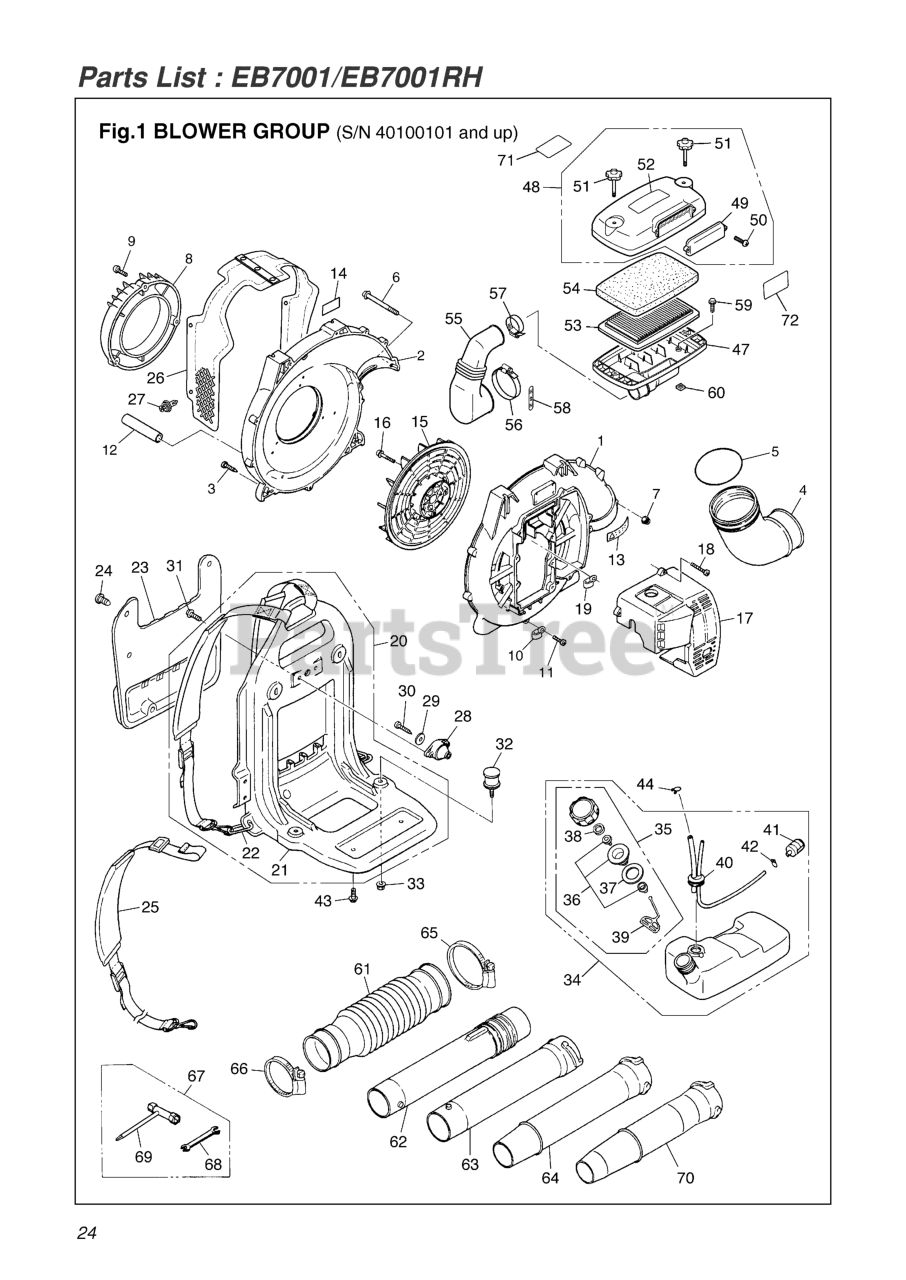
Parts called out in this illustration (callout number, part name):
1	CASE, VOLUTE
2	848-L5C-55B3
3	SCREW, M5 X 25
4	ELBOW
5	O-RING
6	SCREW, M5 X 70
7	NUT (B)
8	COVER, INLET
9	SCREW, M5 X 25
10	CLAMP (RPLS 1140-72231)
12	TUBE (RPLS. 07270-01507)
13	LABEL, CAUTION (RPLS -31910)
14	LABEL, NET
15	FAN
16	BOLT (RPLS 3405-12211)
17	COVER, ENGINE (RPLS -31611)
18	SCREW, M5 X 25
19	CLAMP
20	FRAME ASSY. (REPLACES -32001)
21	FRAME COMP. (RPLS -32100)
22	RING (REPLACES -21120)
23	PAD
24	CLIP (RPLS 3490-21320)
25	BAND ASSY (RPLS 2750- )
26	NET COMPLETE
27	CLIP
28	DAMPER, UPPER
29	WASHER
30	SCREW
31	BOLT, M5 X 16 (RPLS -32540)
32	DAMPER, LOWER
33	NUT, M6
34	TANK ASSY (RPLS. -85100)
35	CAP ASSY (RPLS -85201)
36	HOLDER (REPLACES -85230)
37	PACKING
38	FILTER
39	STOPPER
40	PIPE COMPLETE
41	FILTER ASSY
42	CLIP (REPLACES 2841-31280)
43	SCREW, M5 x 12
44	CLIP
47	BODY, CLEANER (RPLS -82110)
48	COVER ASSY. (EB7001)
49	COVER
50	SCREW, M5 X 25
51	BOLT, KNOB
52	LABEL, CLEANER
53	ELEMENT (PAPER)
54	ELEMENT (FOAM) (RPLS -82320)
55	HOSE
56	BAND
57	BAND
58	LABEL, CHOKE
60	NUT
61	HOSE
62	SWIVEL-JOINT (REPLACES -51200)
63	PIPE, STRAIGHT
64	PIPE, END
65	CLAMP
66	CLAMP (RPLS 3050-13230)
67	TOOL SET
68	SPANNER, 8 X 10 (RPLS 2540- )
69	WRENCH, SOCKET
70	KIT, NOZZLE (USE 2756-51221)
71	LABEL
